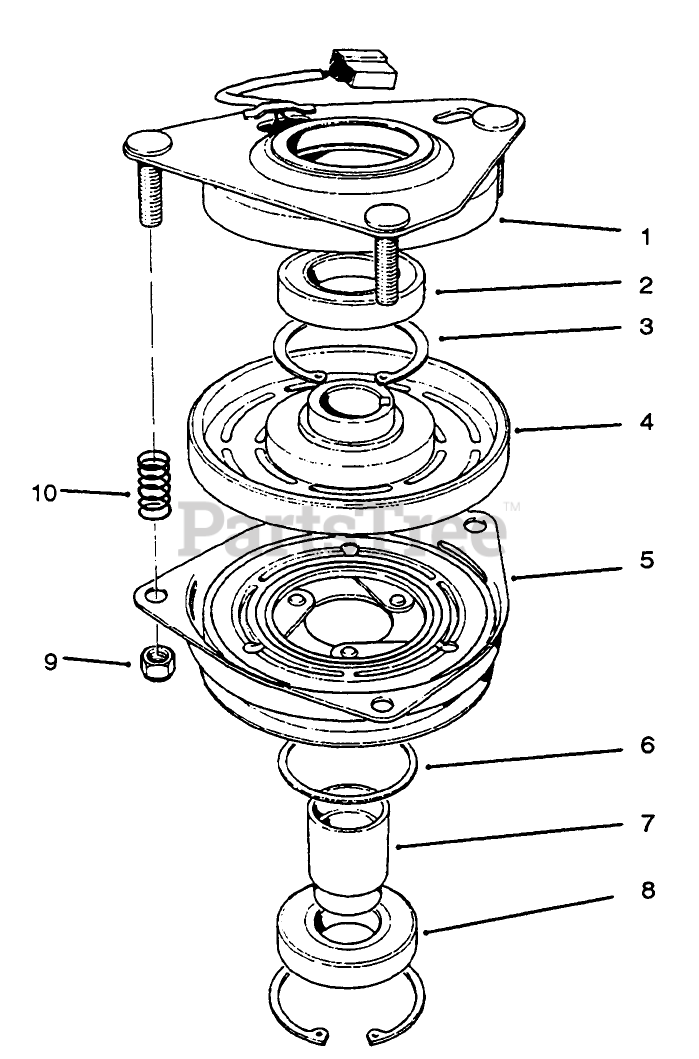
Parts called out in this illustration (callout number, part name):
1	Field Ass-y (Incl. Ref. #2 & 3)
2	BEARING-FIELD
3	RING-RETAINING
4	Field Coil, Rotor & Bearing Assembly (Incl. Ref. # 1)
5	Armature & Pulley Assembly (Incl. Ref. #3, 6, 7, & 8)
6	SPACER-BEARING, PULLEY
7	COLLAR-BEARING
8	BEARING-PULLEY
9	NUT-HEX
10	SPRING
